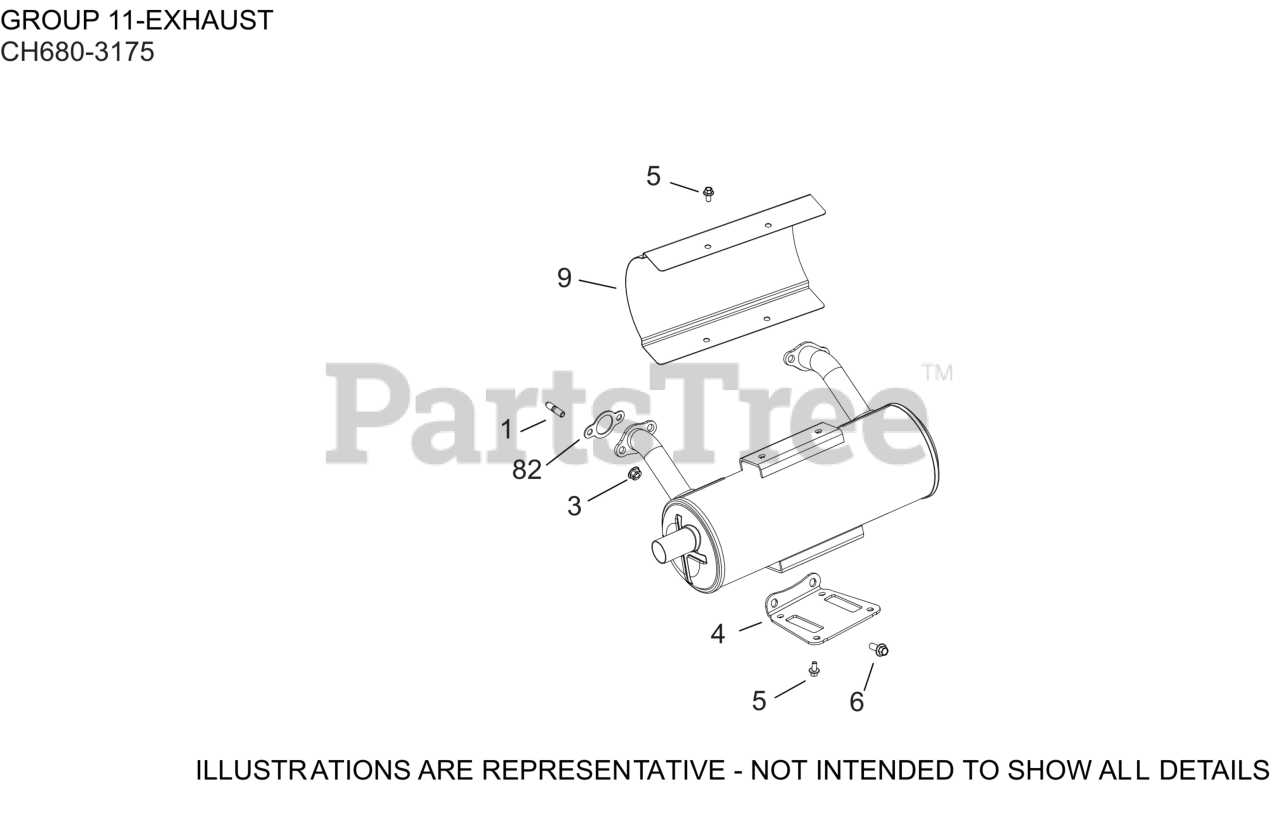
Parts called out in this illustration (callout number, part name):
1	STUD, METRIC EXHAUST
3	NUT, FLG M8X1.25
4	BRACKET, MUFFLER
5	SCREW, FLG M6X1.0X12
6	SCREW, FLG M8X1.25X20
9	SHIELD, ALUM HEAT (LH/CH TWIN)
82	GASKET, EXHAUST MANIFOLD
